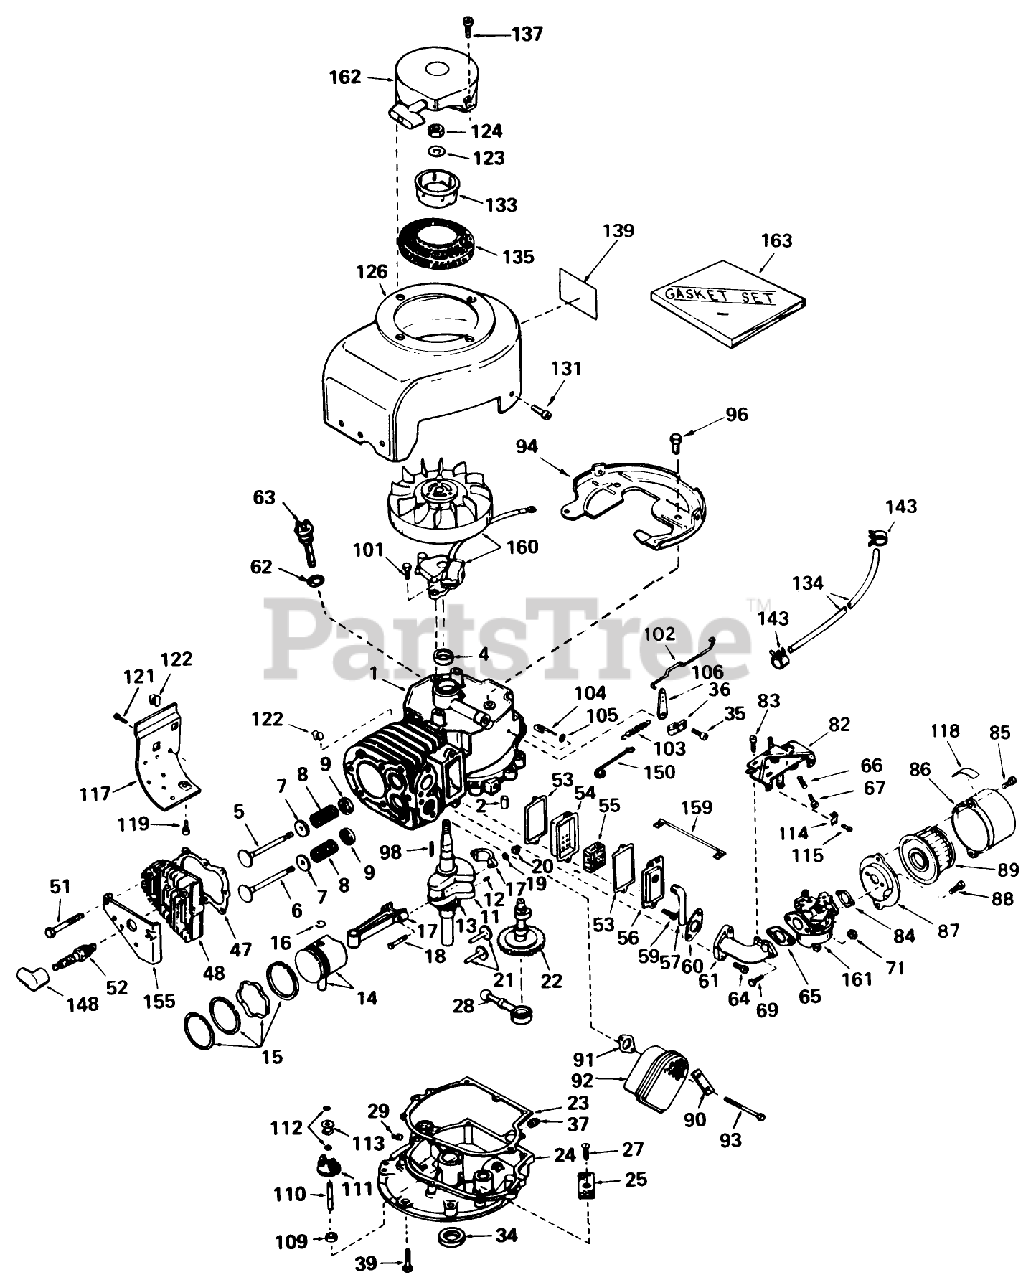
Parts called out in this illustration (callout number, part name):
1	33237A FRONT SCOOP
2	Pin-Dowel
4	Seal, Oil
5	Valve, Intake (Standard)(Incl. No. 9)
5	Valve, Intake (1/32" oversize)(Incl. No. 9)
6	Valve, Exhaust (Standard)(Incl. No. 9)
6	Valve, Exhaust (1/32" oversize)(Incl. No. 9)
7	Cap-Spring, Valve
8	Spring-Valve
9	Keeper-Spring, Valve
11	Crankshaft Assy. (Incl. # 12 13)
12	Pin, Groove
13	Gear-Crankshaft
14	Piston Pin Assy. (Standard)(Incl. 2 of No. 16)
14	Piston Pin Assy. (.010 oversize)(Incl. 2 of No. 16)
14	Piston Pin Assy. (.020 oversize)(Incl. 2 of No. 16)
15	Ring Set, Piston (Std.)
15	Ring Set, Piston (.010 Oversize)
15	Ring Set, Piston (.020 oversize)
17	Rod Assy., Connecting (Incl. Ref. #18)
18	Bolt, Connecting Rod
19	Washer
21	Lifter-Valve
22	Screw
23	Gasket-Cover, Cylinder
24	Flange Assy., Mounting (Incl. #25, 27, 34, 37 110)
25	Screen-Oil Filter
27	Screw
28	Pump, Oil
29	Plug-Pipe (Internal Hex, 1/4-18)
34	Seal-Oil
35	Screw
36	Clamp-Lever, Governor
37	Plug-Drain, Oil (SQH 1/4-18)
39	Screw (1/4-20 x 1-1/4)
47	Gasket-Head, Cylinder
48	CYLINDER HEAD
51	Screw Hex Hd. Cap
52	Plug, Spark (Champion RCJ-8)
53	Gasket-Breather
54	Body-Breather
55	Element-Breather
56	Cover-Valve
57	Tube-Breather
59	Screw
60	Gasket-Intake
61	Pipe, Intake
62	Gasket
63	Dipstick, Oil (Incl. No. 45)
64	Screw (T-30, 5/16-18x1-3/32)
65	Gasket
66	Spring-Compression
67	Screw
71	Nut and Lock Washer (1/4-28)
82	Control Assy., Speed (Incl. Nos. 161 162)
83	Screw (10-24 x 9/16)
84	Gasket
85	Screw
86	Body
87	Bracket
88	Screw (10-32 x 1/2)
89	Element
90	62513 SNWTHWR W/284
91	Gasket Exhaust
92	Muffler
93	Screw Hex Hd.
94	Baffle Blower Housing
96	Screw (1/4-20x19/32)
98	Key, Flywheel
101	Screw
102	Link Governor
103	Spring Governor
104	Rod, Governor (Incl. Nos. 146)
105	Washer-Flat
106	Lever-Governor
109	Spacer
110	Shaft, Governor
111	Governor Gear ASM
112	Ring-Retaining
113	Spool-Governor
114	Conduit
115	Screw (10-32 x 3/8)
117	Emnsion, Blower Housing
118	Decal
119	Screw
121	Screw
122	51004 GIL ROTARY TI
123	Washer
126	Housing, Blower
131	Screw, Hex Hd.
133	Cup-Starter
134	Line-Fuel
135	Screen, Air
137	Screw
139	480B GIL SNWTHWR O/
143	Clamp-Line, Fuel
148	Cover-Spark Plug
150	Link Governor Spring
155	Cover-Head, Cylinder
159	Wire, Ground
160	Magneto
161	Carburetor
162	Starter, Rewind
163	Gasket Set
